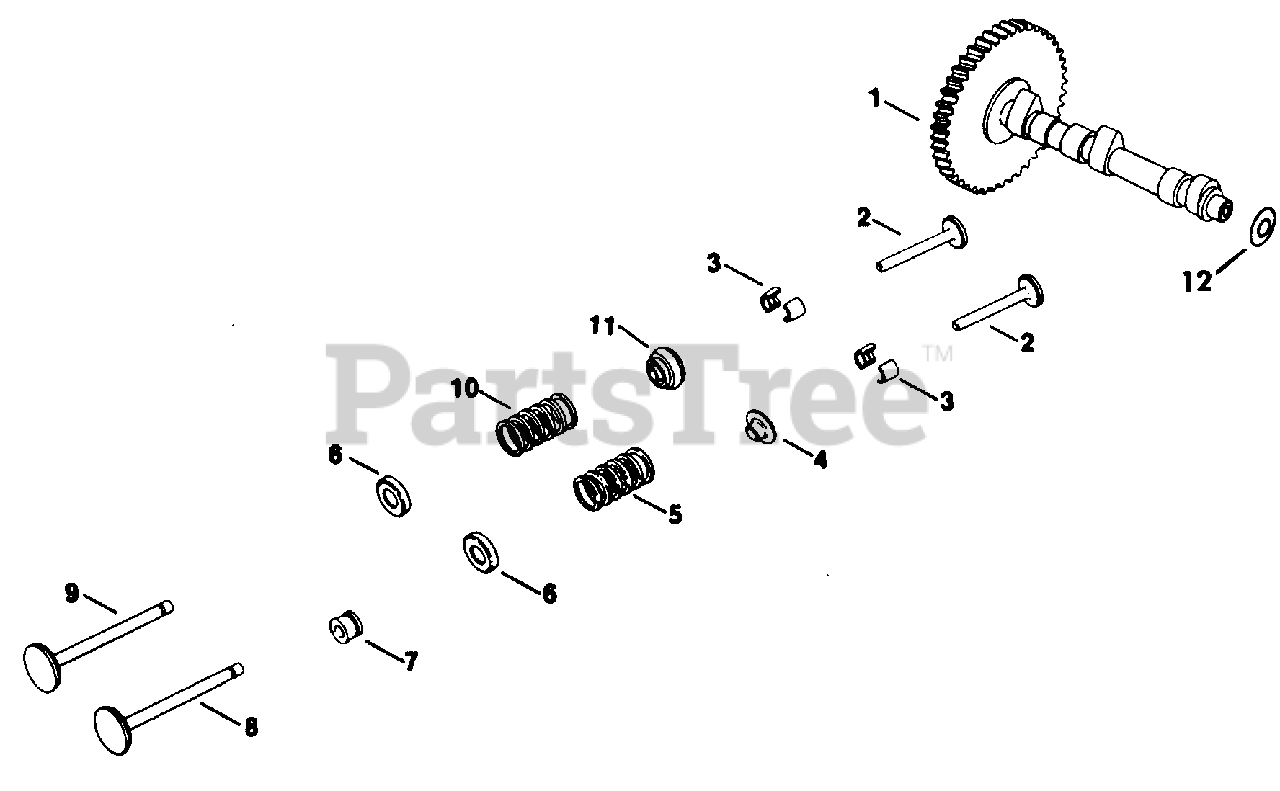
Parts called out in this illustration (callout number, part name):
1	Camshaft w/Gear Assy
2	Tappet, Valve
3	Kit, Retainer
4	Retainer, Intake Valve Spring
5	Spring, Intake Valve
6	Retainer, Spring
7	Seal, Intake Valve Spring
8	Valve, Intake
9	Valve, Exhaust
10	Spring, Exhaust Valve
11	Rotator, Exhaust Valve
12	Shim, Camshaft, .005
